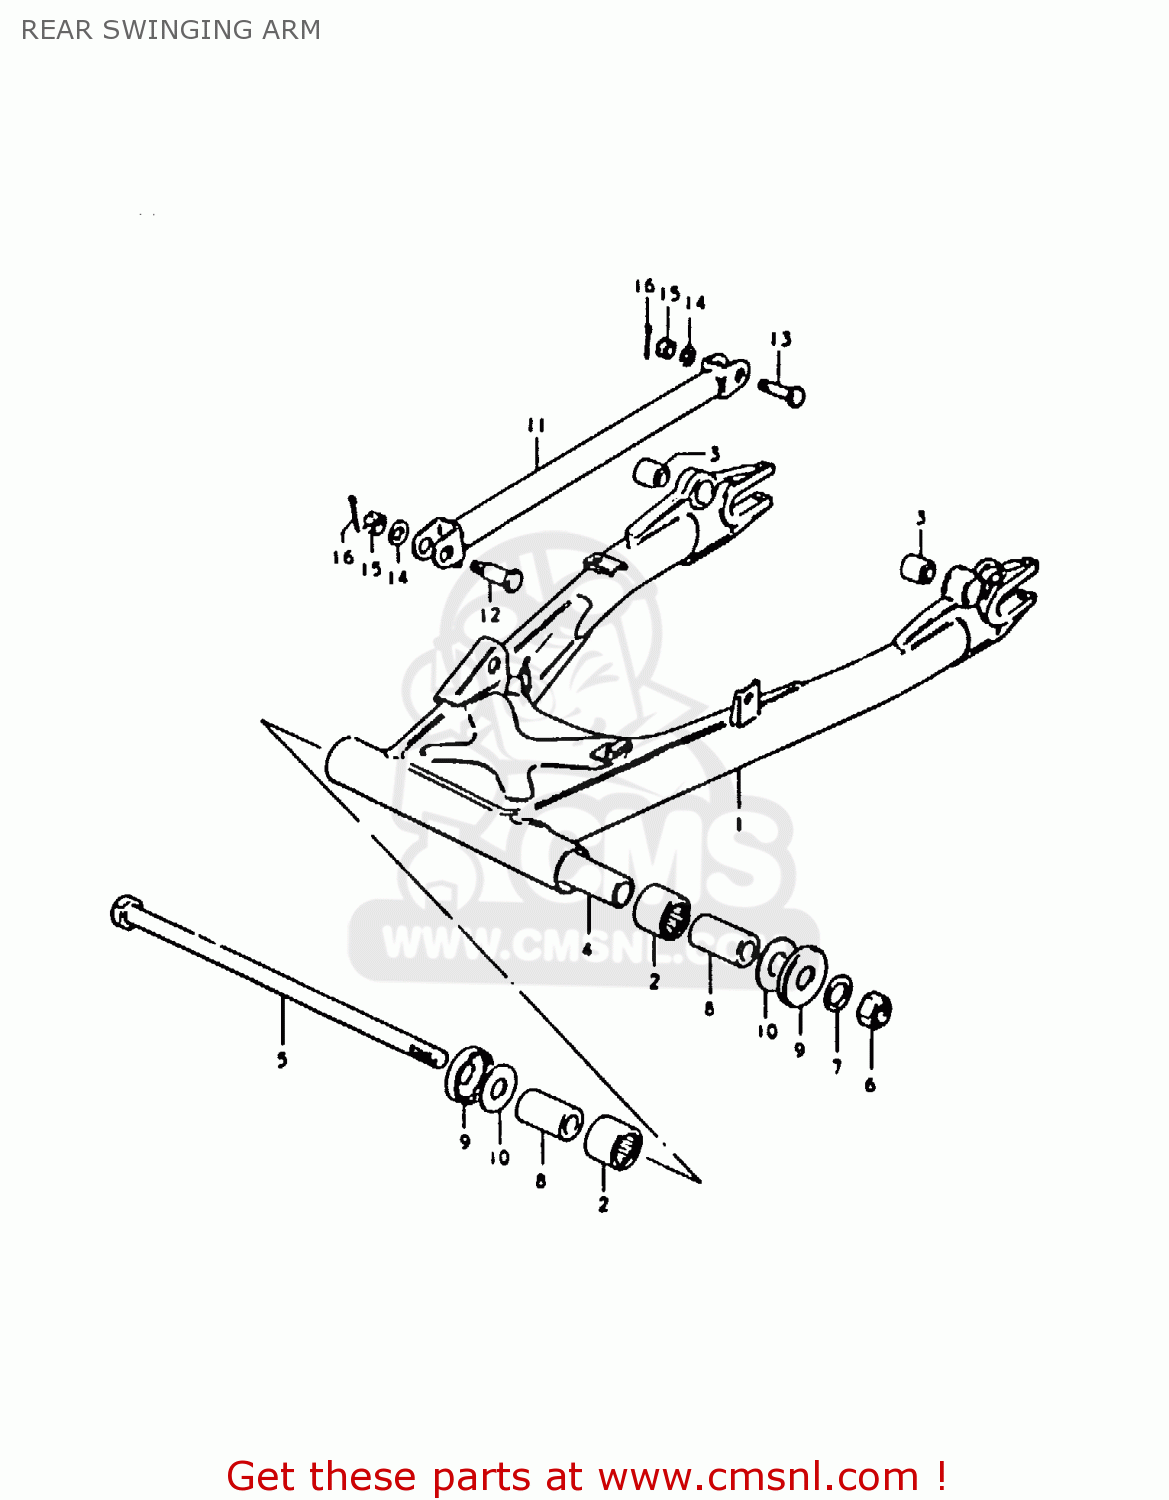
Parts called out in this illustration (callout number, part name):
1	SWING ARM ASSEMBLY,REAR
2	BEARING(25X33X30)
3	BUSH
4	SPACER,RR SWGARM PIVOT CTR
5	SHAFT,REAR SWING ARM
6	NUT 16MM
7	WASHER
8	SPACER,RR SWGARM PIVOT
9	COVER,RR SWGARM DUST SEAL
10	WASHER
11	LINK,REAR TORQUE
12	BOLT
13	BOLT(10X39)
14	WASHER
15	NUT
16	PIN 20X20
